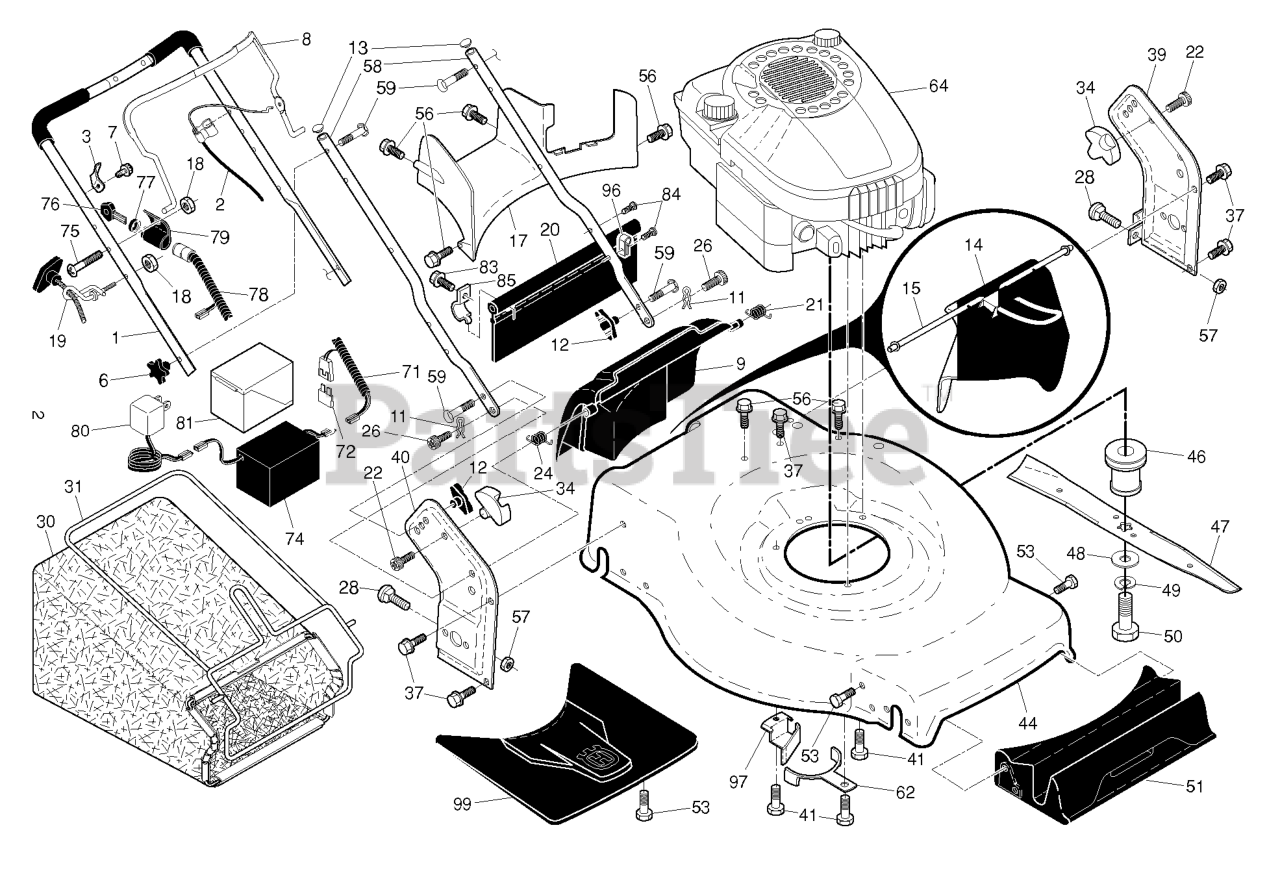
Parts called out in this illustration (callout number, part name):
1	HANDLE.ASM.UPPER.W/GRIP
2	CABLE.MZR.RGD.PLUS.ERG
3	BRACKET.UPSTOP.RT
6	KNOB.HANDLE.PLASTIC.STAR.BLACK
8	BAIL.CONTROL.MZR.BS.ORANGE
9	DOOR.REAR.ASM.22+.HUSQ.FG/RGD
11	COTTER.HAIRPIN.DOOR/HANDLE.PIV
12	KNOB, DEFLECTOR
13	PLUG.PLASTIC.7/8".14-20.GAUGE
14	DEFLECTOR.CHUTE.22+REAR
15	HANDLE DEFLECTOR.22+REAR
17	RP.BAFFLE.REAR.22+.RGD.PL
18	NUT
19	RB GUIDE.ROPE.STD.BLK.ZIN WSL
20	SKIRT.REAR.22PLUS.RGD.LW(2 2MC
21	SPRING.LH.BLACK
22	SCREW.PAN.HEAD.#10
24	SPRING.RH.GRAY
26	SCREW,DOOR/HANDLE.PIVOT
28	BOLT
30	GBAG.A3610247T.SILV.HUSWT.BLUE
31	RB FRAME.GBAG.22PLUS
34	BRACKET.GRASSBAG.ATTACHING.BLK
37	BOLT.5/16HEX.WHS.HD
39	BRACKET.HANDLE.LT.22+.W/DP.GRE
40	RP.BRACKET.ASM.HANDLE.RT.22+.
41	BOLT 3/8-16X1-1/8
44	HOUSING.22+.RWD.HD.WO/PORT.ORN
46	ADPTER.BLAD.25M.VS.22PLU.STAR
47	BLADE.22+.PREMIUM/PREC.FGD/RGD
48	WASHER,HARDEN
49	LOCKWASHER
50	SCREW, HEX HD 3/8-24 X 1-3/8
51	BAFFLE.FRONT.22PLUS.PLASTIC RP
53	SCREW.HI-LO.5/16 X.75
56	SCREW.HX.13X.750
57	NUT.FLANGE.5/16
58	HANDLE.LOWER.22+BT.2PC.GRY
59	BOLT, HANDLE 5/16-18X1.75
62	BRACKET.ENG/BELTKEEPER
71	HARNESS.22+BATTERY.RWGD
74	RB BATTERY.12 VOLT.22+ RWGD
75	SCREW.(COMBINATION CONTROL)
76	KEY.MOLDED
77	NUT.CAP.SNAP-ON.KEY START
78	KIT.CONTROL.KEY.ASM.22+.RWGD
79	HOUSING.WIRING.HARNESS
80	RP CHARGER.12V.0.1A
81	BOX.BATTERY.22+RGD.GREY
83	TAPPING SCREW
84	FASTENER.PUSH.O.250X0.783
85	BRACKET.SKIRT.22+.BZP
96	CLIP.CABLE.BLK
97	BRACKE.BELT.GUIDE.22+
99	COVER.ASM.FRONT.SHROUD.HUSQ.
